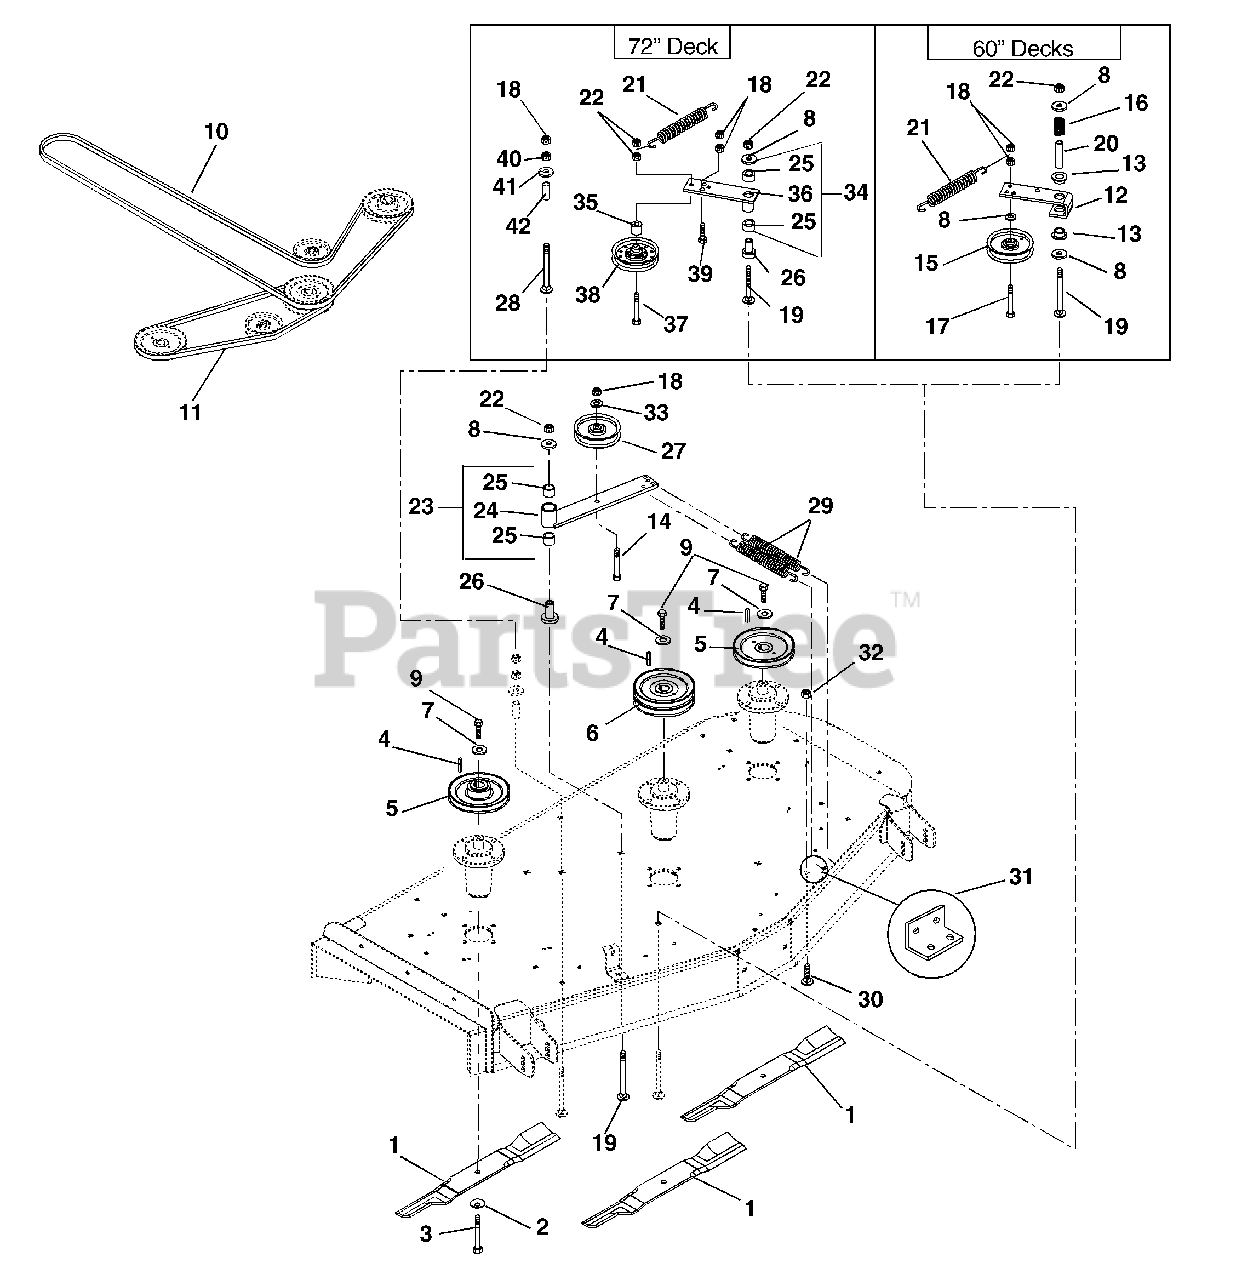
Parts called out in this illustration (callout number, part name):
1	Blade, 72" Mower Tungsten Hi-Lift
1	Blade, 60" Mower Tungsten Hi-Lift
1	Blade, 60" Mulching Tungsten
1	Blade, 72" Mulching Tungsten
2	Washer-Bellville .63 x 1.625 x .14
3	Bolt-Hex .62-18 x 1.75 Grade 8
4	Key-Straight .25 x 1.00 x .25
5	Weldment, Spindle Sheave 7.00
5	Weldment, Spindle Sheave 6.00
6	Weldment, Sheave (Double) 7.25
6	Weldment, Spindle Sheave (Double) 6.25
7	Washer, Cupped, Serrated .375
8	Washer-Flat-Steel .531 x 1.25 x .100
9	Bolt-Hex .38-16 x 1.00 Grade 8
10	V-Belt, B-RMA 69.81 x .625
10	V-Belt, B-RMA 63.40 x .625
11	V-Belt, B-RMA 28.62 x .625
11	V-Belt, B-RMA 23.94 x .625
12	Arm,Idler Pivot
13	Bushing-Flange-Nylon .762 x 1.0 x .58 x 1.48
14	Bolt, Hex .38-16 x 3.00 Grade 5
15	Idler-V 4.00 x .377
16	Spring-Compression .085 x .80 x 1.00
17	Bolt-Hex .38-16 x 2.25 Grade 5
18	Nut-Locking-Center .38-16
19	Bolt-Round Head Square Neck .50-13 x 3.50
20	Spacer .560 x .750 x 2.437 Steel
21	Spring, Extension
22	Nut-Locking-Center .50-13
23	Assembly, Idler Pivot Arm
24	Weldment, Idler Pivot Arm
25	Bearing, 1.00 x 1.12 x .75
26	Bearing, Pedistal Powdered Metal
27	Idler-Flat 4.00 x .38 (2.00 W)
28	Bolt-Round Head Square Neck .38-16 x 2.75 Grade 5
29	Spring, Extension
30	Bolt-Round Head Square Neck .38-16 x 1.00 Grade 5
31	Bracket, Spring
32	Nut-Locking-Nylon .38-16
33	Washer-Flat-Steel .375 x 1.125 x .065
34	Assembly, Idler Arm-Ground Drive
35	Spacer .51 x .75 x .62
36	Weldment, Idler Arm Ground Drive
37	Bolt-Hex .50-13 x 2.50 Grade 5
38	Idler-Flat-Pulley 6.75 x .510
39	Bolt-Hex .38-16 x 1.25 Grade 5
40	Nut-Locking-Nylon .38-16
41	Washer-Flat-Steel .406 x .812 x .065
42	Spacer .380 x .625 x 1.50
